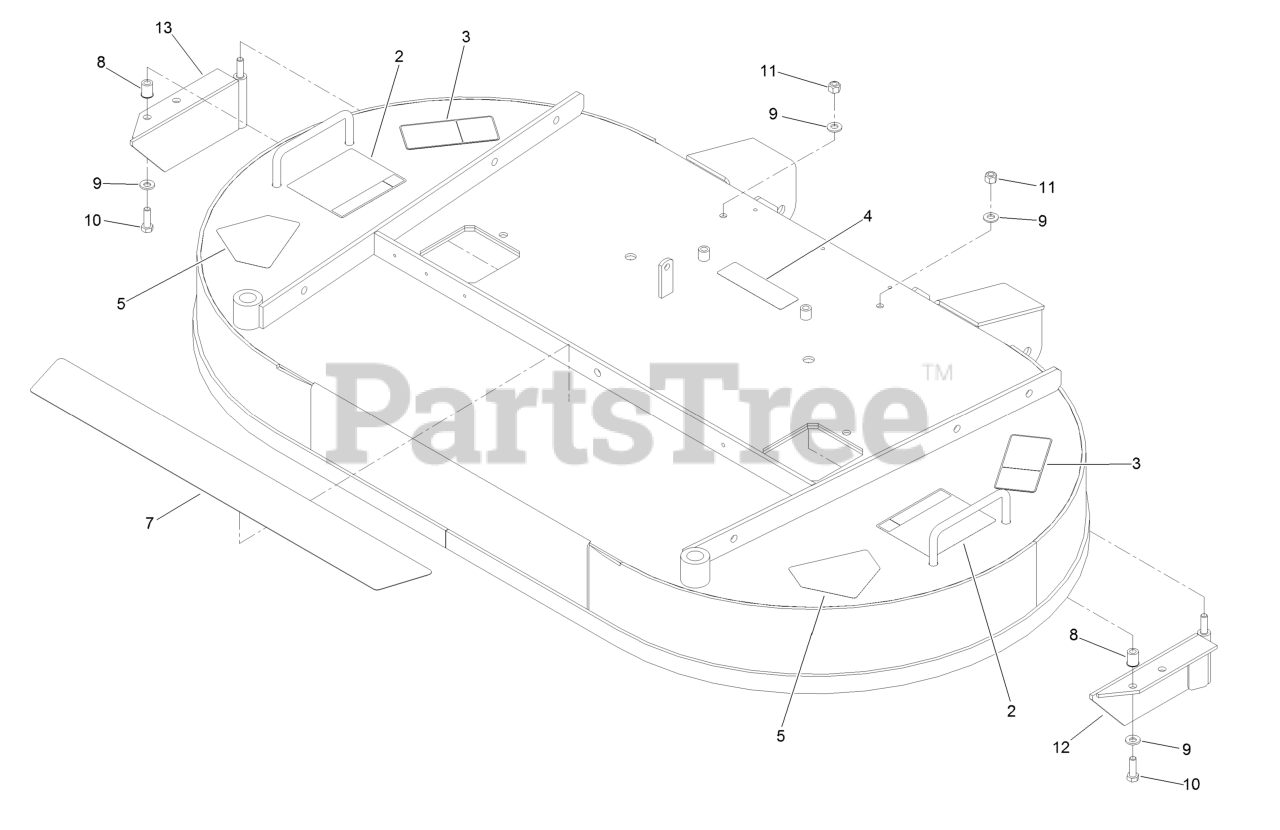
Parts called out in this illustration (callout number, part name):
2	Decal-Height Adjust, Cutting
3	Decal-Torque, Blade Bolt
4	Decal-Missing, Cover
5	Decal-Danger
7	Pad-Anti Skid
8	Nut-Insert
9	Washer-Spring
10	Screw-HH
11	Nut-Lock, NI
12	Baffle-LH
13	Baffle-RH
